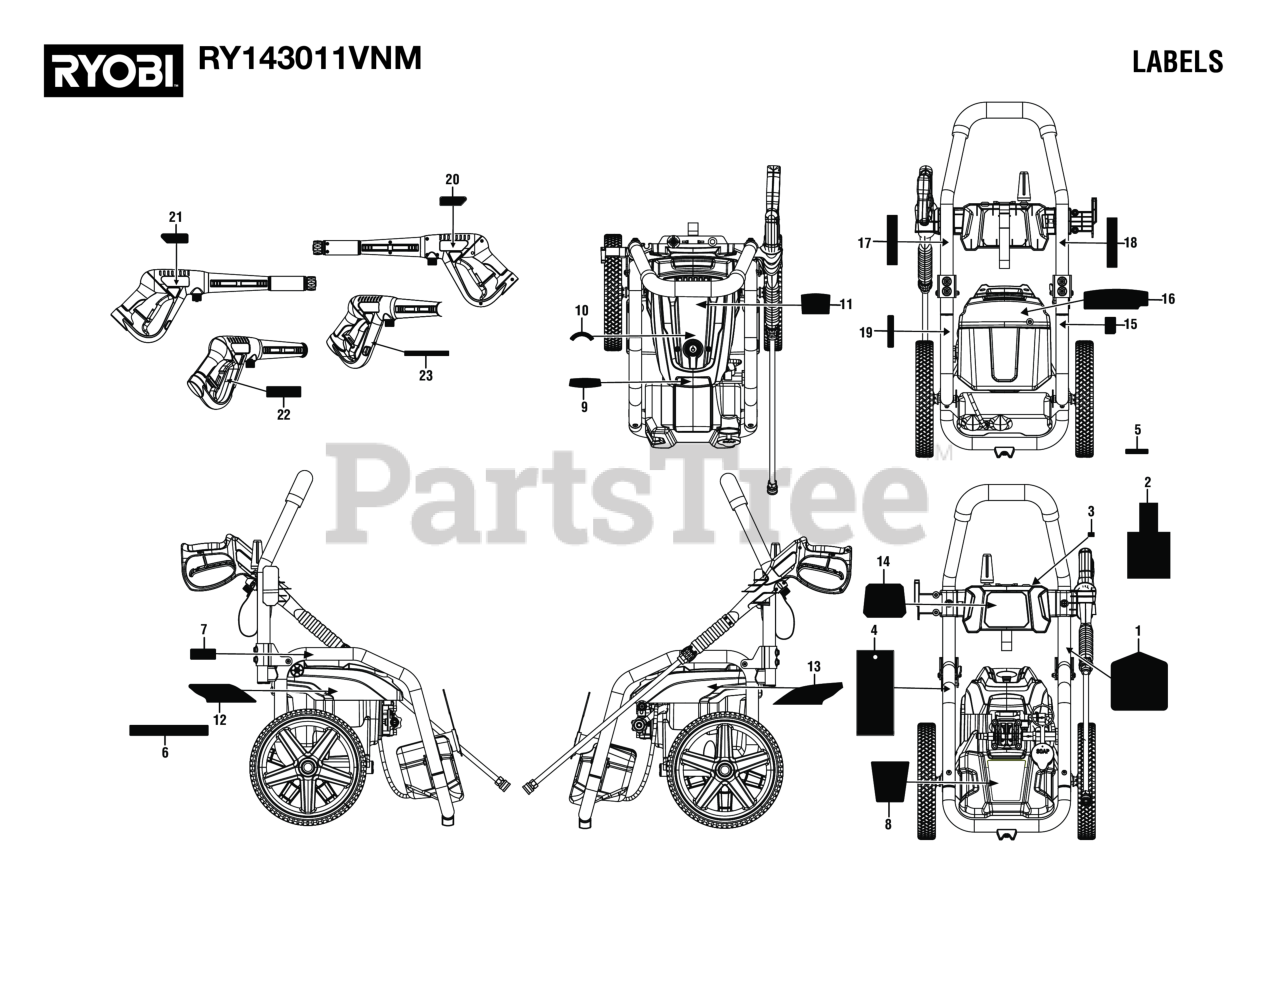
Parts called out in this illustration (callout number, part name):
1	Nozzle Hangtag
2	Cordwrap Warning Label
3	Nozzle Storage Label
4	Danger Hangtag (Spanish)
5	Power Cord Label
6	Outlet Cord Wrap Label
7	Handle Release Label
8	Detergent Tank Label
9	Brushless Label
10	On / Off Label
11	High Performance Label
12	Danger Label
13	Icon/Danger Label
14	Performance Label
15	QR Code Label
16	Danger Regulatory Label
17	Starting Instruct 1 Label
18	Starting Instruct 2 Label
19	Inquires Label (Ryobi)
20	Trigger Handle Warning Label (English)
21	Clutch Cover Label
22	Label (Trigger Handle Warning, French & Spanish)
23	Trigger Handle Data Label
